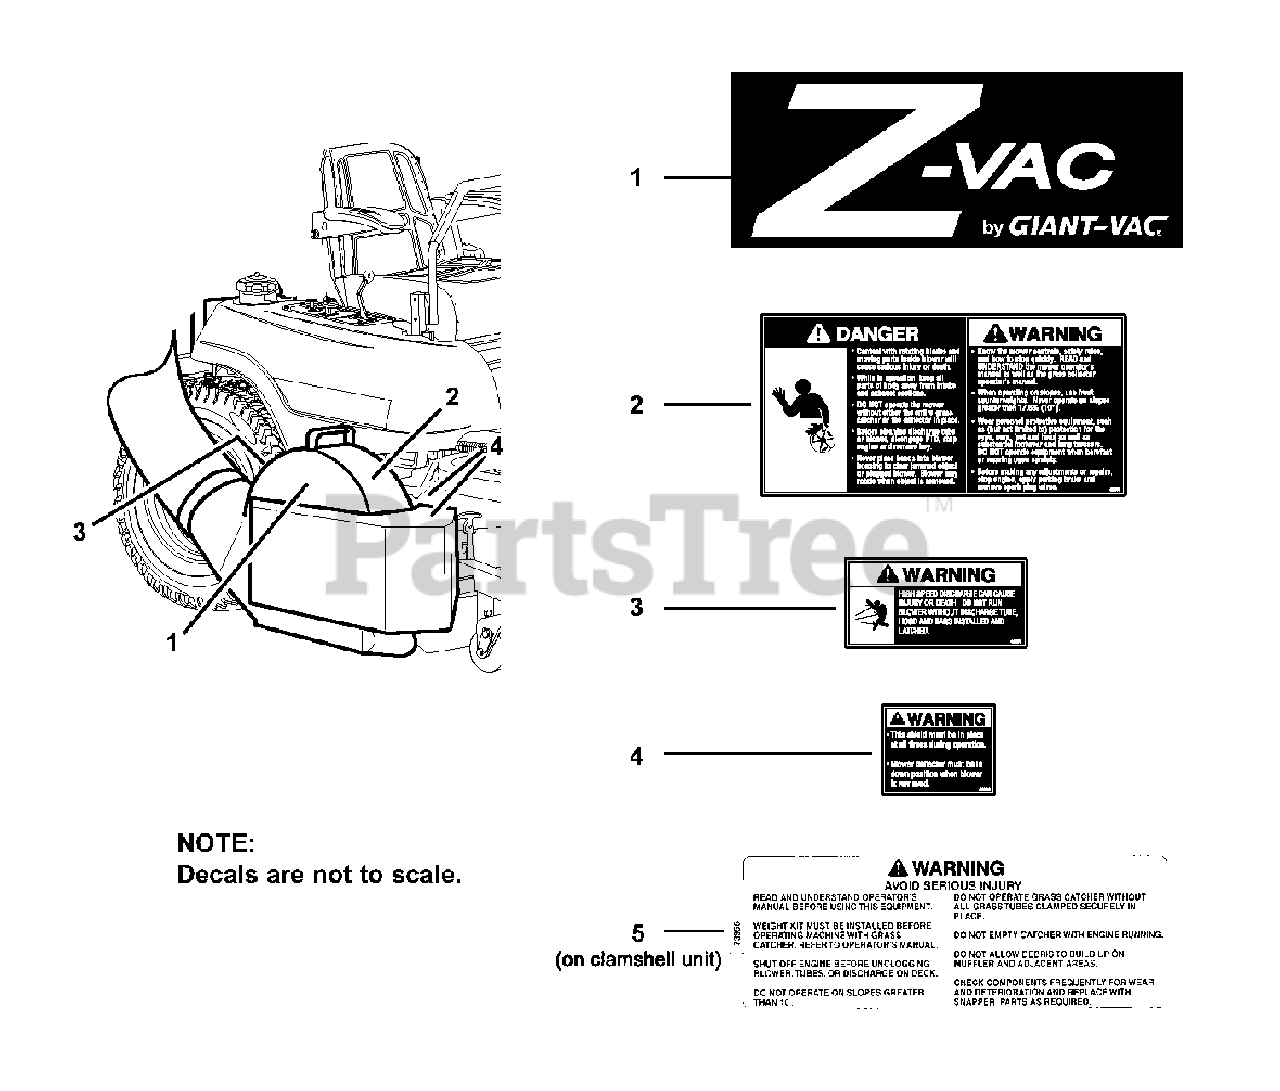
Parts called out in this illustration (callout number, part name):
1	DECAL, Z-Vac
2	DECAL, Danger, Fast-Vac
3	DECAL, Warning, Fast Vac
4	DECAL, Warning, Fast-Vac
5	DECAL, Warning, Billboard (on clamshell unit)
